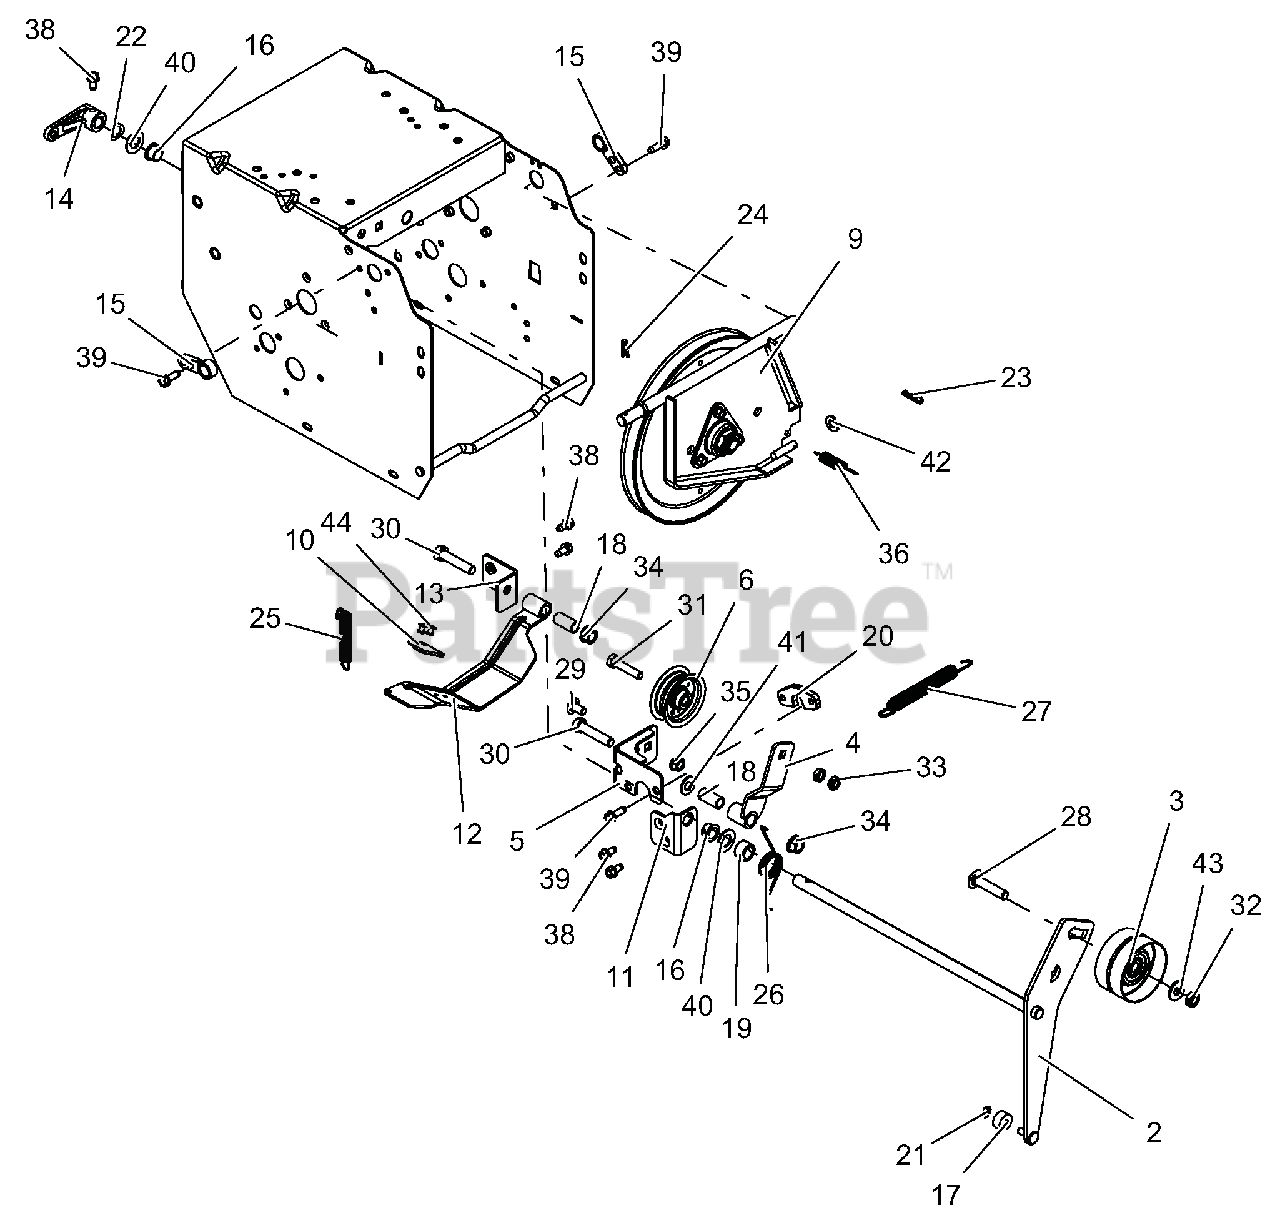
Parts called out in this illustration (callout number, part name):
2	WELDMENT, ATTACHMENT IDLER ARM
3	IDLER, FLAT-2.75 OD X .375 ID
4	ARM, TRACTION IDLER
5	WELDMENT, FRAME BRACKET
6	KIT, FLAT IDLER
9	PLATE, SWING - ASSEMBLY
10	PAD, BRAKE
11	BRACKET, MOUNT - IDLER ARM
12	BRAKE ARM W/PAD
13	BRACKET, BRAKE MOUNT
14	ARM, CLUTCH - ATTACHMENT
15	SUPPORT BUSHING, SWING GATE
16	BUSHING, POLYLINER-.50 SPLIT
17	BSHG,SLV .265 X .625 X .375
18	BSHG-SLV .385X.500X1.045
19	BSHG-SLV .510X.751X.475
20	SPACER, SWING GATE
21	RG-RTNG-EXT .250X.010
22	WSHR-WAVE .50X.75X.015 .13FRHT
23	PIN-HAIR INT .08X.18X1.18 YWZC
24	CLIP, SPRING
25	SPRING-EXT .047 X .438 X 1.85
26	SG-TORS .075 X .955
27	SPRING, SWIVEL HOOK EXTENSION
28	@BLT-RHDSSQNK .38-16X1.75 G5YZ
29	@BLT-RHDSSQNK .31-18X.62 G5YZ
30	@BLT-HEX .38-16X1.75 GR5 YWZC
31	@BLT-HEX .31-18X1.50 GR5 YWZC
32	@NUT-LK-CTR-JAM .375-16 YWZC
33	@NUT-LK-CTR-JAM .31-18 YWZC
34	@NUT-LK-TOP-FLG .38-16 YWZC
35	@NUT-LK-TOP-FLG .31-18 YWZC
36	SPRING, EXT. .043X.438X1.64
38	SCR-TAP .25-20X.50 HWH TR YWZ
39	SCR-TAP-PM .25-20X.75 TR YWZ
40	WSHR-FL-STL.531X1.00X.063 YWZC
41	@WSHR-FL-STL.406X.812X.065 YWZ
42	@WSHR-FL-STL.344X.688X.065YWZC
43	@WSHR-FL-STL.38X.875X.083 YWZC
44	RVT-POP .187 YZ
